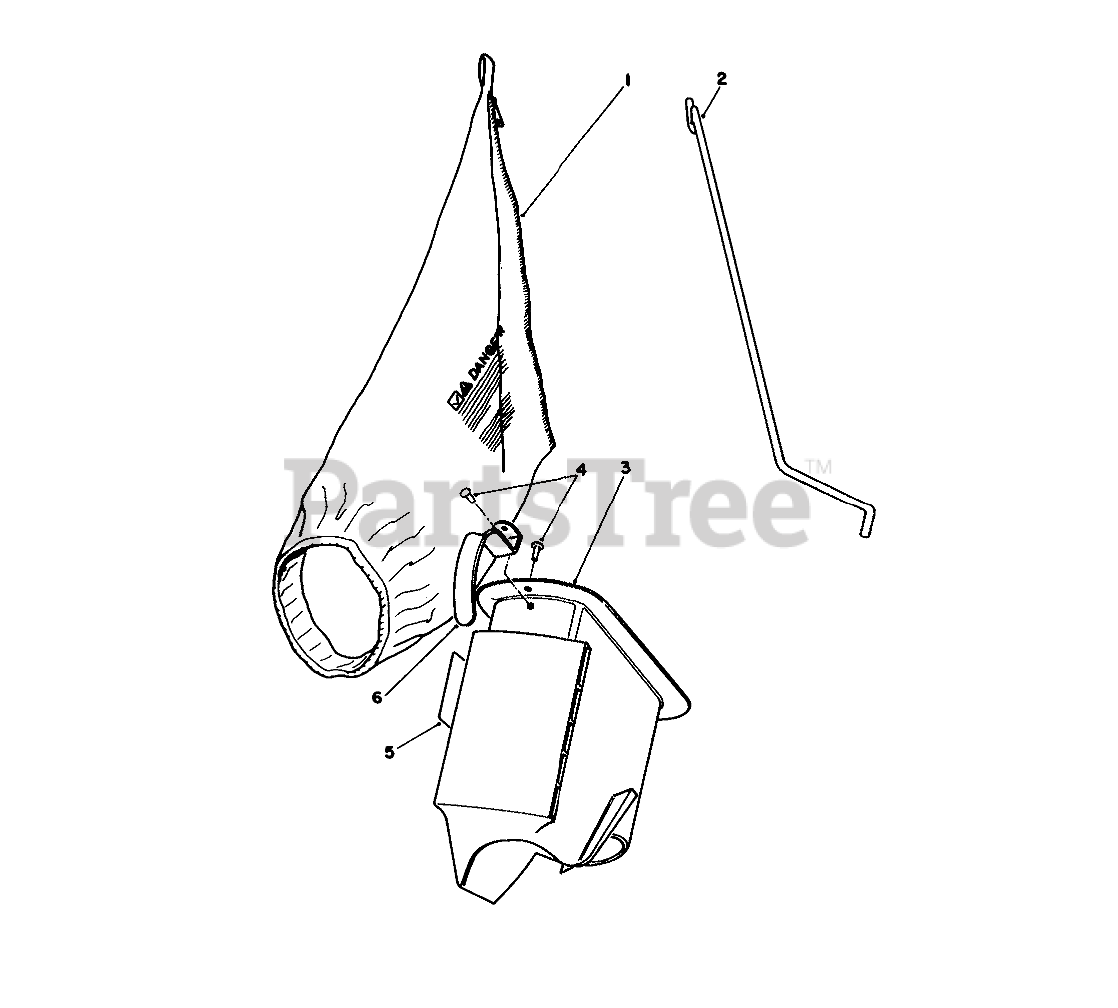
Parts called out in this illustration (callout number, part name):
1	Grass Bag
2	BAG ROD
3	Grass Chute (Incl. Ref. #4 & 6)
4	RIVET 3/16 X 7/16
5	BAG CHUTE DECAL
6	HANDLE-GRASS CHUTE
